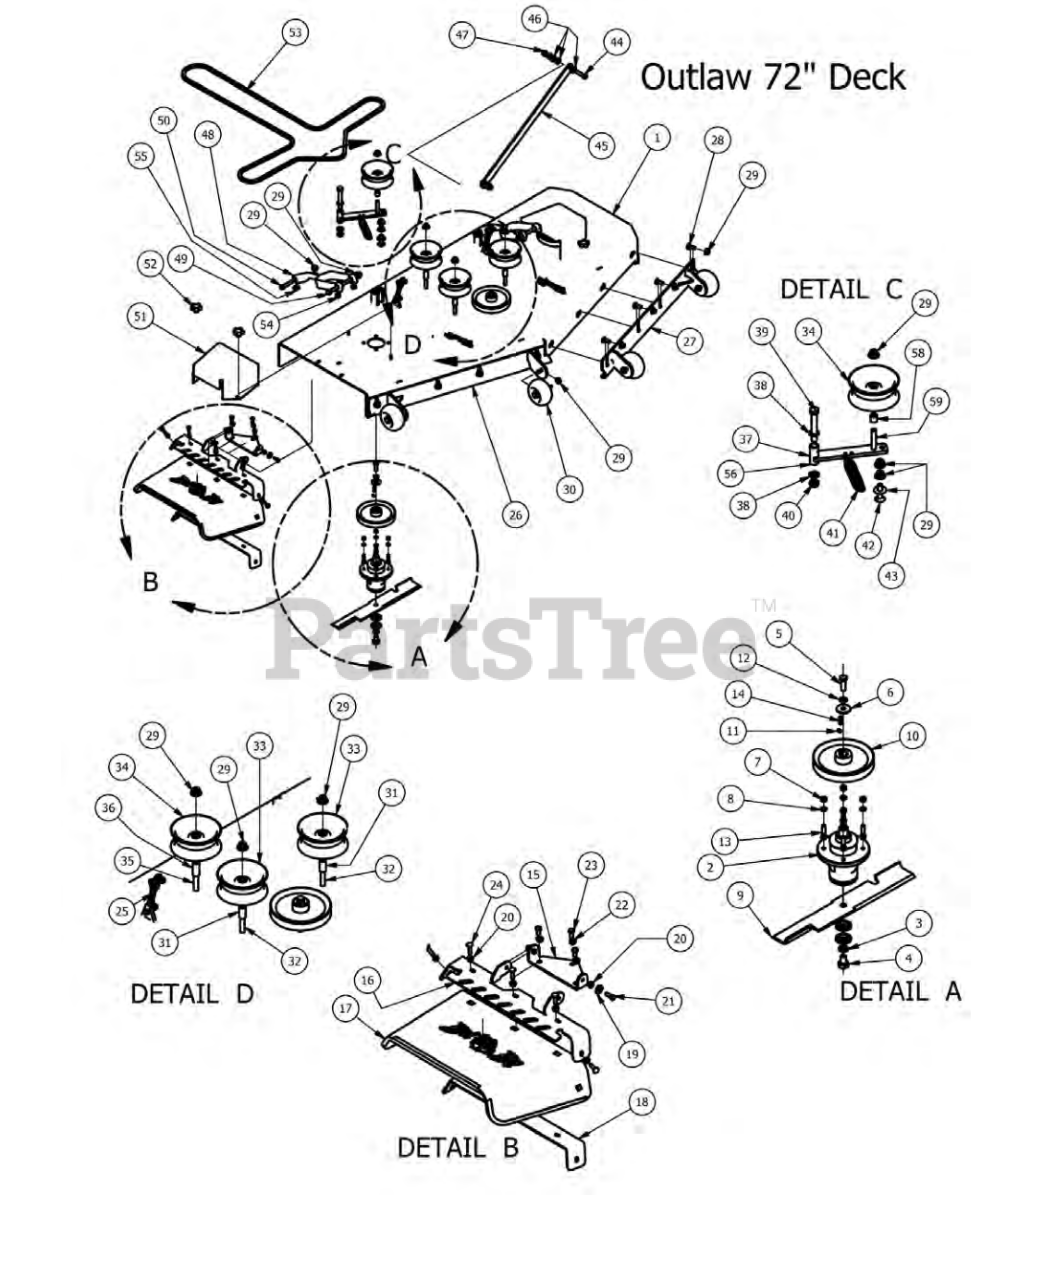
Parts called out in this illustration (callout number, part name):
1	72" Outlaw Deck
2	Double Bearing Spindle
3	5/8" Lock Washer
4	5/8" x 1 1/2" Grade 8 Bolt
5	1/2"-20 x 1 1/2-Grade 5 Fine Thread Bolt
6	1/2 Belleville Washer
7	3/8-16 Hex Nuts Zinc
8	3/8 Lockwasher Zinc
9	72" High Lift Fusion Blade
10	7" Deck Pulley
11	3/8" Set Screw
12	1/2" Lock Washer
13	3/8" x 1 1/2" Hex Bolt
14	1/4" x 1" Key
15	Discharge Chute Hanger (deck mounted)
16	60" Upper Discharge Chute
17	Rubber Discharge Chute
18	60" Lower Discharge Chute
19	360 ID Plastic Washer
20	5/16" Flange Nut Zinc W/Serrations
21	5/16" x 1" Bolt
22	3/8" Flange Nut
23	3/8" x 3/4" Hex Bolt
24	5/16" x 1 1/4" Carriage Bolt
25	2-Link Adjustable Deck Hange
26	72" Deck Adustable Front (Right)
27	72" Deck Adjustable Front (Left)
28	1/2" x 1 1/4 Carriage Bolt
29	1/2-13 Nylon Insert Flange Nut
30	Deck Wheel
31	Pup Pulley Spacer
32	1/2 x 3 1/2 Flange Bolt Grade 8
33	5 3/4" Deck Idler Pulley
34	5 3/4 Flat Idler-32FI-92-008 Pulley
35	1/2" x 4" Bolt (Grade 8)
36	13/4" Pulley Spacer
37	Deck Idler Bracket
38	.635 ID Plastic Washer
39	5/8" x 4" Hex Bolt:
40	5/8" Nylock (1/2 Jam)
41	2009 Deck/Pump Idler Spring
42	1/2 x 2" Carriage Bolt
43	1/2" Flat Washer
44	1/2-13x2 GR 5 Hex Bolt
45	Outlaw Panhard Link
46	.505 Nylon Spacer
47	1/2" Flange Nut
48	Deck Arm Assembly
49	1/2" x 5 1/2" Bolt
50	1/2-13X 2-1/4 GR. Hex Bolts
51	72 Spindle Cover
52	5/16" Knob
53	8202 Belt for 72" Outlaw
54	Flange Bushing For Deck Arm upper
55	Flange for Lower Deck Arm
56	Deck Idler Complete Assembly Componets 29,34,37,58,59
57	Double Bearing For Spindle
58	3/4 OD x 1/2 ID x 3/4 Length
59	1/2-13 x GR 5 Hex Bolt Zinc
